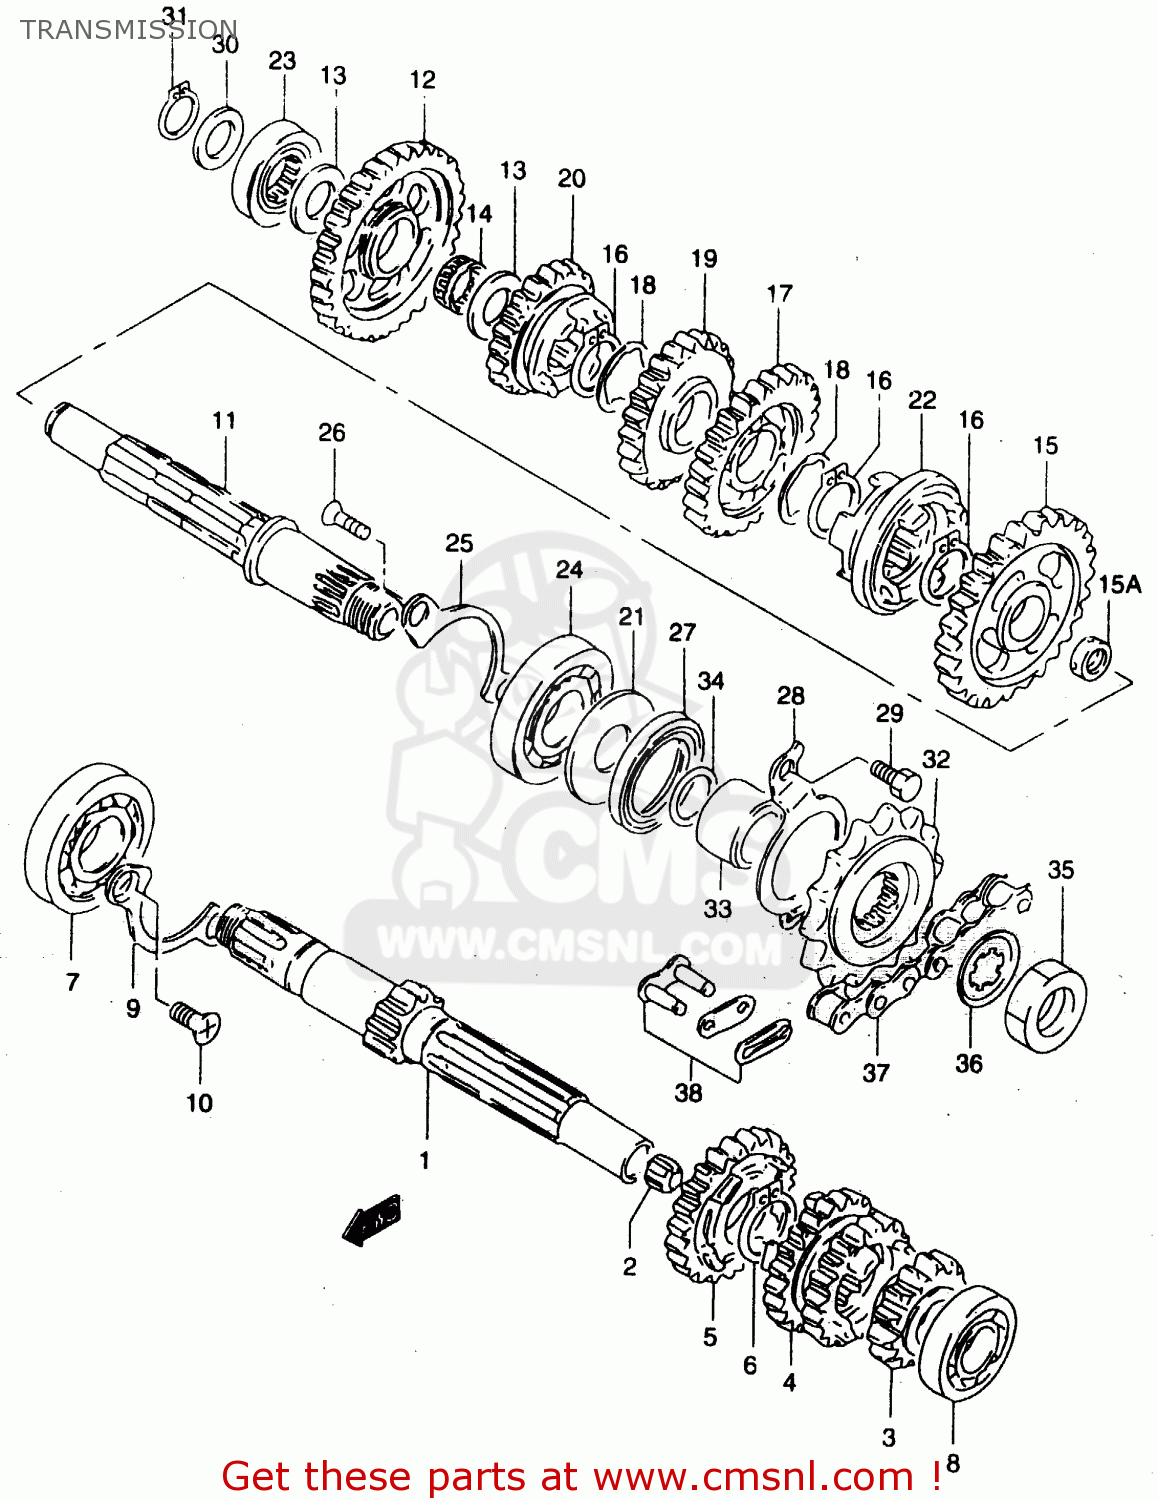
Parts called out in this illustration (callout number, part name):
1	SHAFT,COUNTER (NT:11)
2	BUSH
3	GEAR,2ND DRIVE(NT:14)
4	GEAR,3RD & 4TH DRIVEN(NT:19/21
5	GEAR,FIFTH DRIVE (NT:23)
6	CIRCLIP
7	BEARING(20X47X14)
8	BEARING
9	RETAINER,DRIVE SHAFT BEARING
10	SCREW
11	SHAFT,DRIVE
12	GEAR,FIRST DRIVEN (NT:33)
13	WASHER
14	BEARING(15X19X7.8)
15	GEAR,2ND DRIVEN(NT:26)
15A	BUSH,2ND DRIVEN GEAR
16	CIRCLIP
17	GEAR,3RD DRIVEN(NT:26)
18	WASHER,LOCK
19	GEAR,4TH DRIVEN(NT:23)
20	GEAR,5TH DRIVEN(NT:21)
21	WASHER,OIL SEALING
22	WHEEL,SLIDING DOG
23	BEARING(15X33X12)
24	BEARING(20X47X14)
25	RETAINER,DRIVE SHAFT BEARING
26	SCREW
27	SEAL,OIL(27X40X6)
28	RETAINER,DRIVE SHAFT OIL SEAL
29	BOLT
30	SHIM(15X20X1)
31	CIRCLIP
32	SPROCKET (NT:15)
33	SPACER,ENGINE SPROCKET
34	O RING(D:2.4,ID:19)
35	NUT
36	WASHER
37	CHAIN(RK428FDZ,132LE)
38	JOINT(RK)
